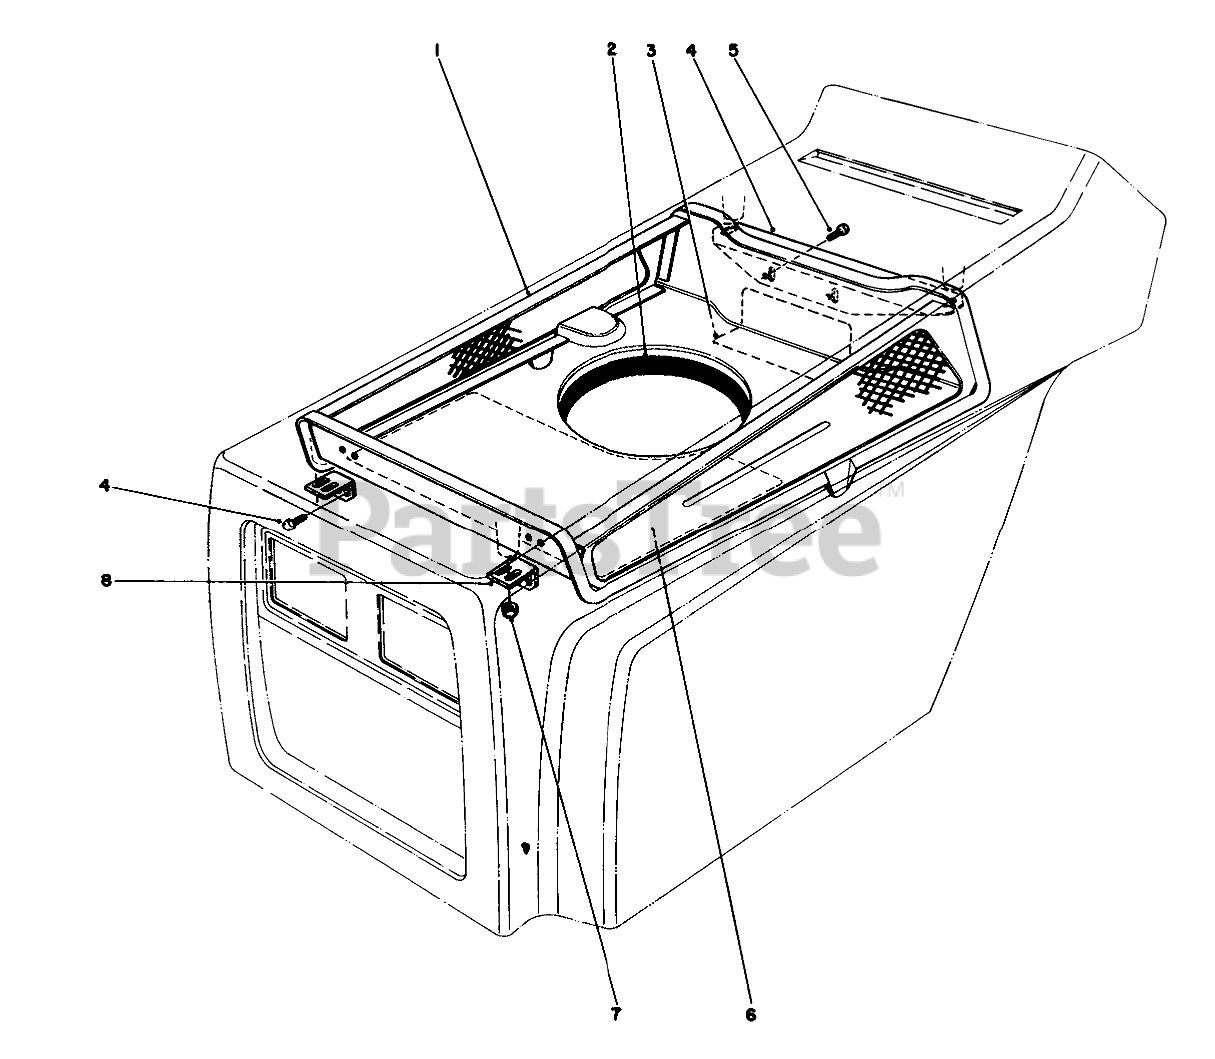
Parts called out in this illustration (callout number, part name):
1	Duct Hood
2	Seal Engine
3	BELT DECAL
4	Bracket Rear Duct Support
5	SCREW-HWHTF
6	Decal Service
7	NUT-LOCK, NI
8	Bracket Front Duct Support
